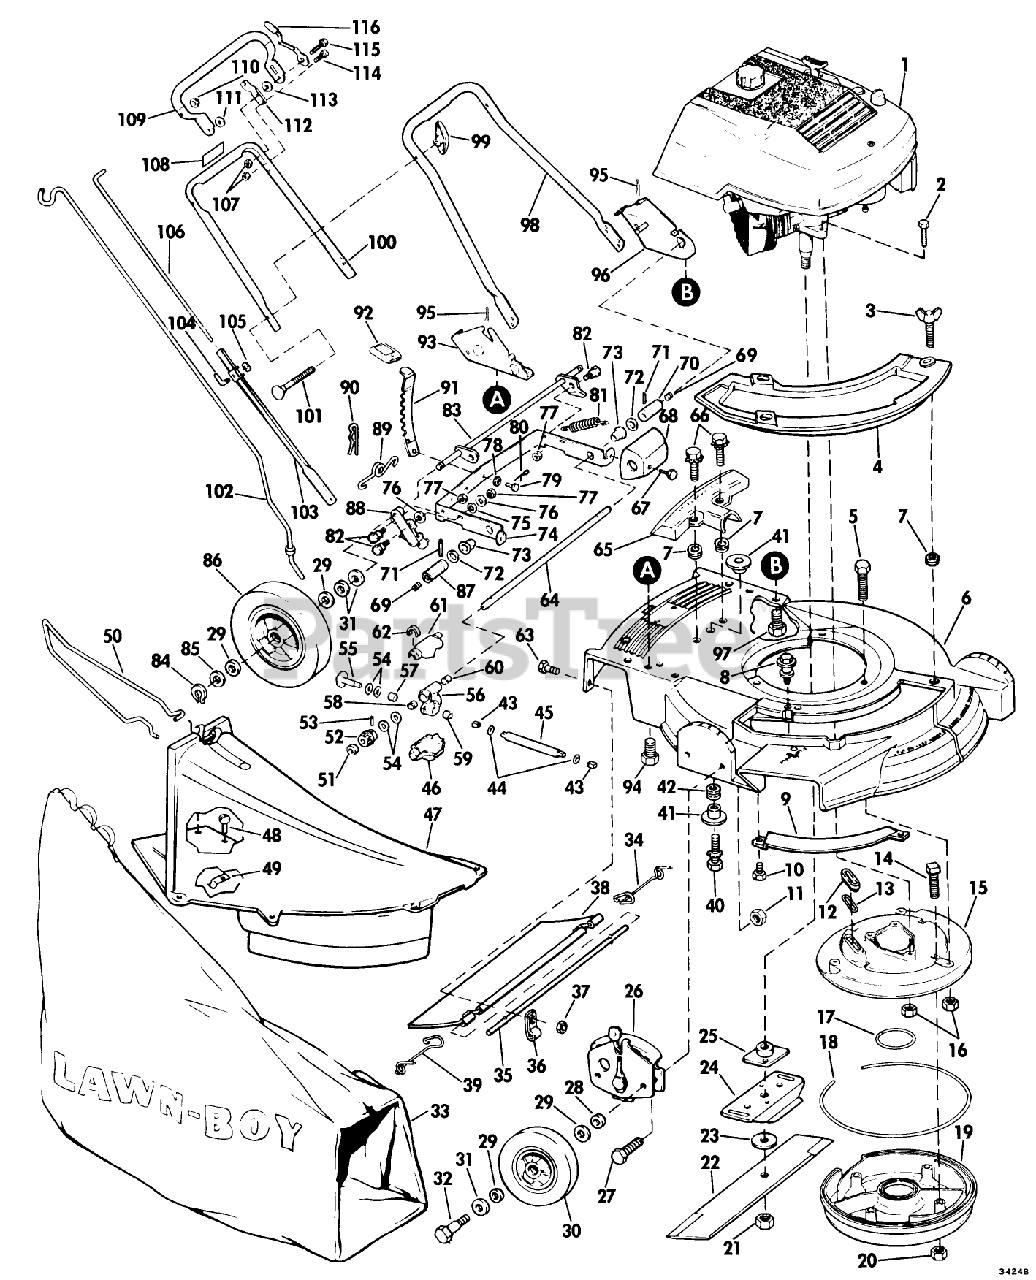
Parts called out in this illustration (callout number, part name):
2	BOLT F
3	WING SCREW LAWRE
5	SCREW V
9	BAR-TOE
11	NUT
12	SLEEVE
13	GASKET S
14	SCREW
16	NUT-LOCK F
18	Gasket Muffler (outside)
20	LOCKNUT E
21	NUT-BLADE
23	WASHER
25	PLATE AND COLLAR ASM
28	WASHER WROUGHT
29	WASHER
31	SPACER
32	BOLT WHEEL
33	ORD LB 89802 WHOLE GOODS
34	SPRIG T/SHLD ASOC
35	ROD 21" ADVANCE
36	CLAMP ROD KMC
39	SPRING;TRAILING SHIELD RH
41	SPACER ECK PRES
42	GROMMET
43	BUSHING
44	O Ring
51	WASHER
53	ROLL PIN
54	THRUST WASHER
57	NEEDLE BEARING
61	GEAR COVER UPPER
65	COVER
66	SCREW SEMS TRM HEX HD
68	GUARD
69	GREASE PLUG
71	PIN
76	WASHER S
77	STOP NUT
78	WASHER SPRING LAR
79	PIN
81	SPRING
82	BOLT RB&W
84	RET RING
85	SPACER
89	SPRING N.A.S
91	LEVER
92	KNOB
94	SCREW
95	HAIR PIN
97	SCREW
99	NUT-WING
100	HANDLE
102	ROD GRASSBAG
106	ROD CONTROL
111	WASHER M
115	BOLT RB&W
116	KNOB & SPRING
